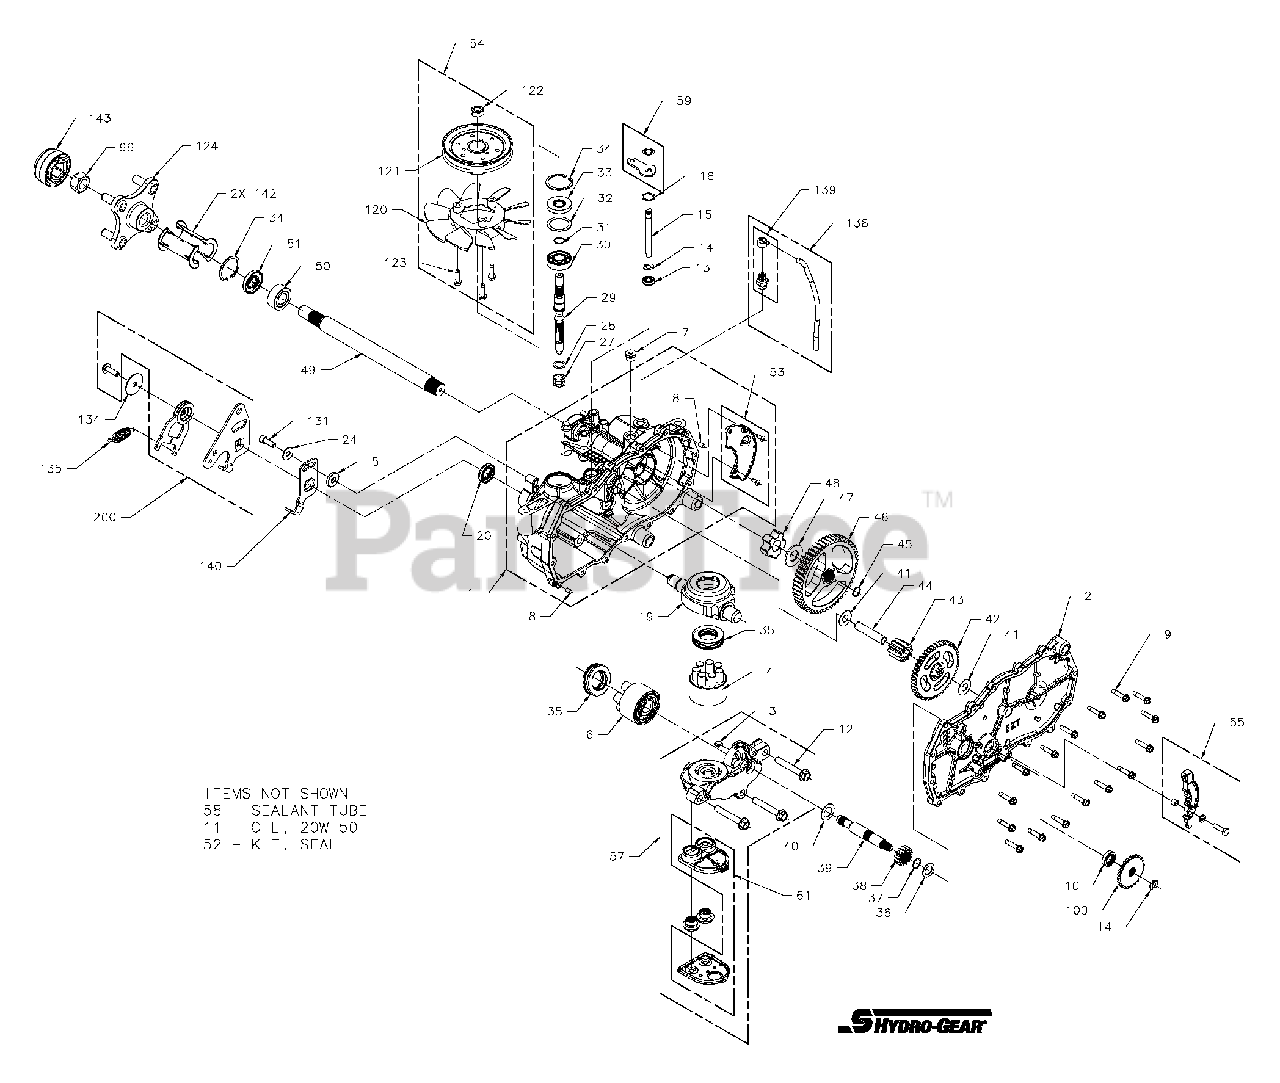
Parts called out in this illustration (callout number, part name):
1	ASSEMBLY, MAIN HOUSING-RH
2	ASSEMBLY, SIDE-RH
3	PLATE, BYPASS
4	ASSY, BLOCK 7 PISTON
6	KIT, 10 CC BLOCK
8	PIN, STAINLESS, HEADLESS
9	HFHCS 1/4-20 X 1.25 (SELF-TAPPING)
10	KIT, SEAL
13	SEAL, LIP .375X.75X.25
14	SEAL, LIP .375X.75X.25
15	ROD, BYPASS
16	RING, RETAINING .750 INT
19	TRUNNION, SWASHPLATE
20	SEAL, LIP 18X32X7
27	SPRING-HELICAL COMPRESSION
28	WASHER. THRUST .59 X .79 X .04
29	SHAFT, INPUT
30	BRG, BALL 17X40X12
31	RING, RETAINING WIRE .561 ID
32	SPACER
33	SEAL, LIP 17X40X7
34	RING, RET 1.56 INT
35	BEARING. THRUST 30 X 52 X 13
37	RING, RETAINING
39	SHAFT, MOTOR
43	GEAR, 10T JACKSHAFT
44	PIN, JACKSHAFT
45	RING, RET - SPIRAL
46	GEAR, 52T BULL
48	BEARING, SLEEVE (INBOARD)
49	SHAFT, AXLE
50	BUSHING, SLEEVE
51	SEAL, LIP .750 X 1.577 X
52	KIT, SEALS AND RETAINING
53	KIT, EXPANSION PLATE, RH
54	KIT, FAN-PULLEY
55	BRAKE ARM, EZT #70865
58	SEALANT TUBE 10.1OZ.
59	KIT, BYPASS ARM
61	KIT, FILTER
99	NUT, HEX, LOCK 3/4-16
100	DISC, COG BRAKE
120	FAN, 7", 10 BLADE
121	FAN PULLEY KIT 4.5X1.625
124	KIT, HUB 1/2-20
131	SHCS, 5/16-24 X 1.00 (PATCH)
134	WASHER
135	SPRING, EXTENSION
138	KIT, BREATHER ASSEMBLY
139	KIT, BREATHER
140	ARM, NEUTRAL
142	TUBE, AXLE, 2.86, SPLIT
143	CAP, AXLE
200	KIT, RTN ASSEMBLY, RH
